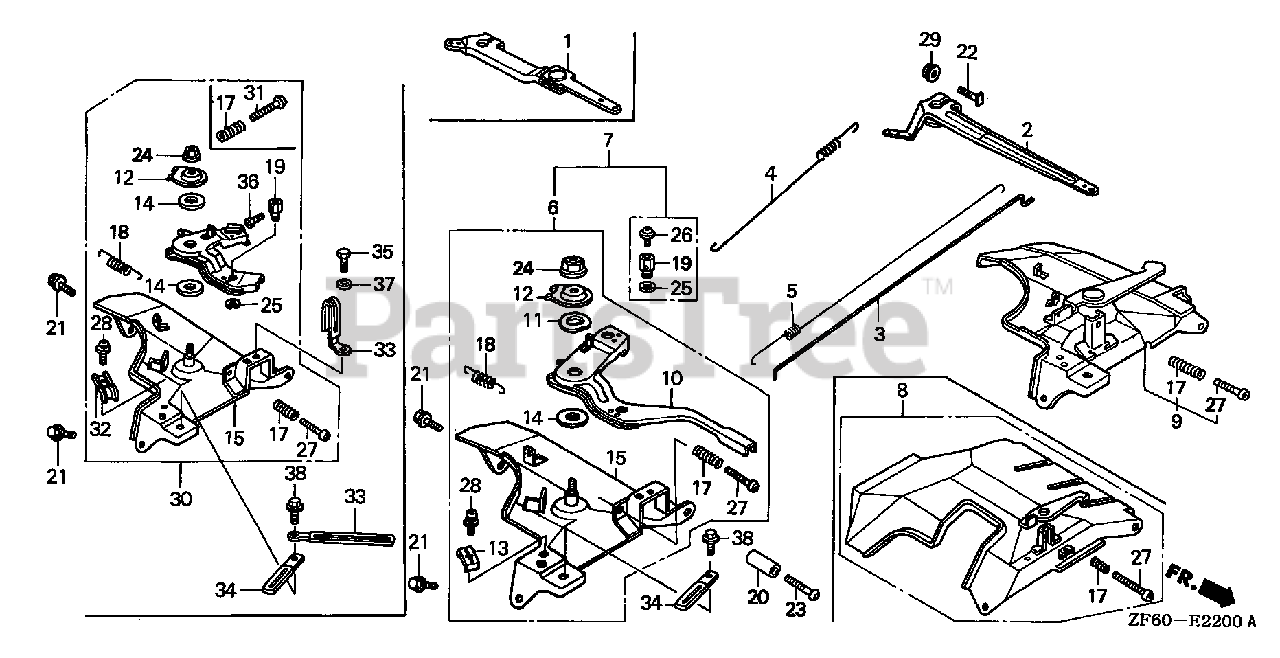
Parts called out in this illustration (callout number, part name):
2	ARM, GOVERNOR
3	ROD, GOVERNOR
4	SPRING, GOVERNOR (L=137.5MM)
5	SPRING, THROTTLE RETURN
6	CONTROL ASSY. (REMOTE)
10	LEVER, CONTROL
11	SPRING, LEVER
12	WASHER, CONTROL LEVER
13	HOLDER, CABLE
14	SPACER, CONTROL LEVER
15	BASE, CONTROL
17	SPRING, CONTROL ADJUSTING
18	SPRING, CABLE RETURN
21	BOLT, FLANGE (6X12) (CT200)
22	BOLT, GOVERNOR ARM
24	NUT, SELF-LOCK (6MM)
27	SCREW, PAN (5X32)
28	SCREW, PAN (5X16)
28	SCREW-WASHER (5X16)
29	NUT, FLANGE (6MM)
